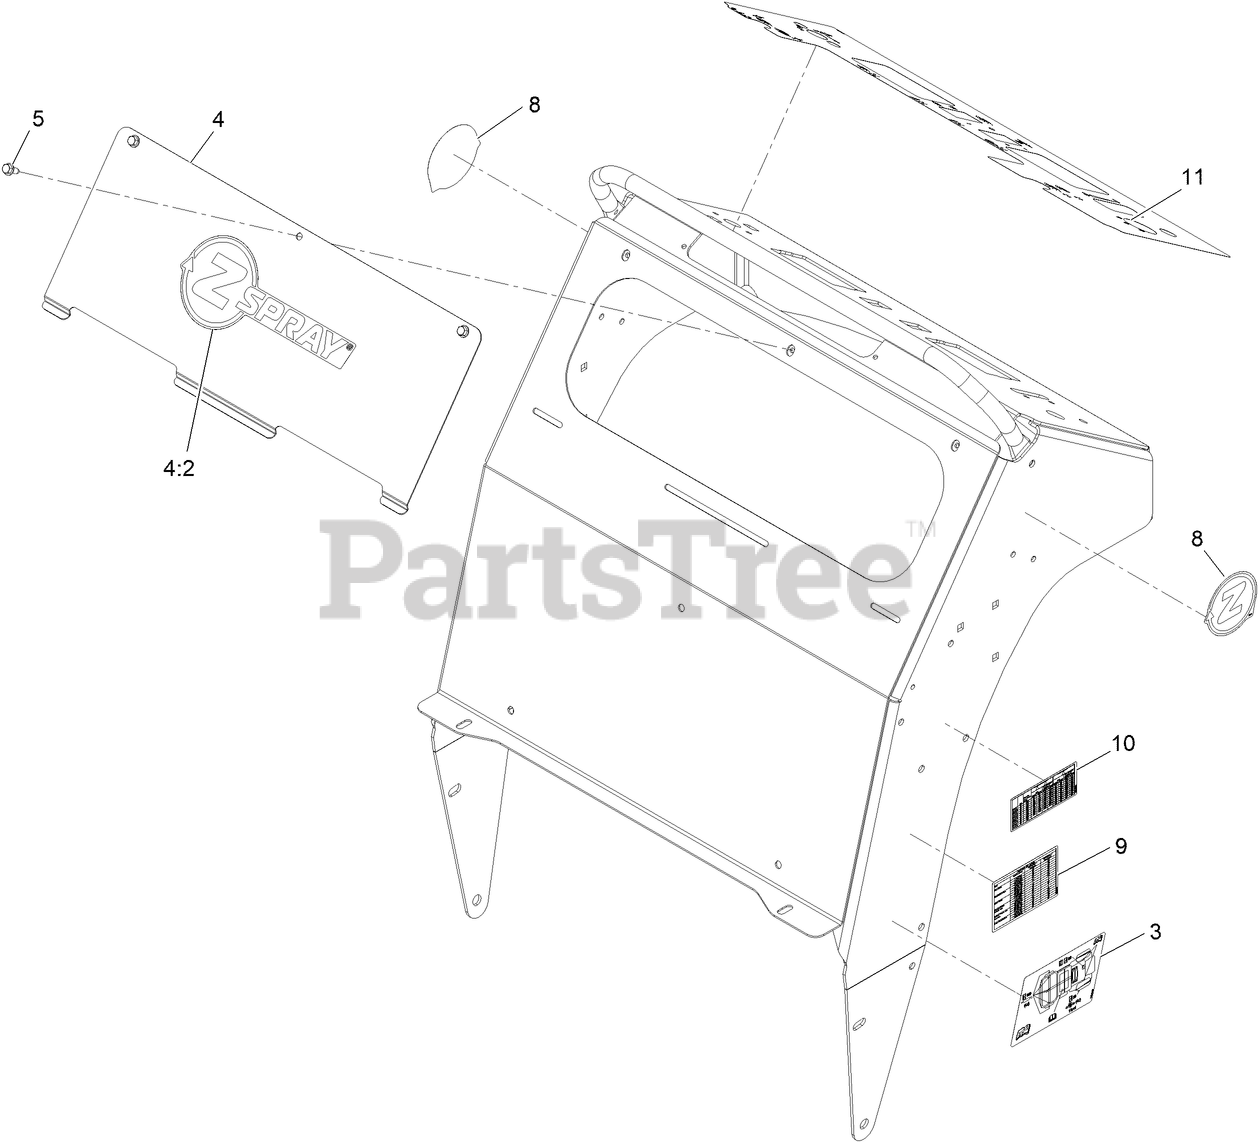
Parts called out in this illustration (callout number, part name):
3	DECAL-SERVICE AID
4	ACCESS PANEL W/ DECAL
4:2	Decal-Z-Spray
5	SCREW-HWH
8	Decal-Z-Logo
9	Decal-Spread Chart
10	Decal-Spray Chart
11	Decal-Control
